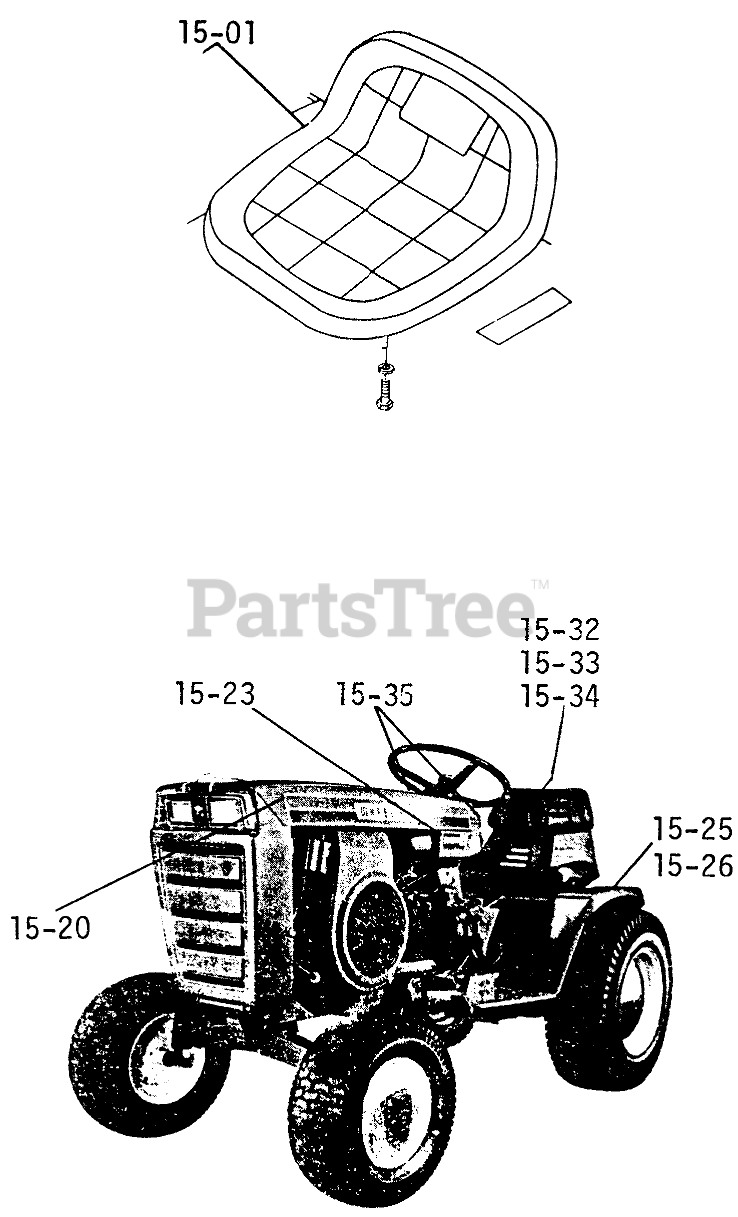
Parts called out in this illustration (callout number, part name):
15-01	Bolt Hex 5/16-18
15-01	Lockwasher
15-23	Decal-800 Automatic
15-23	Decal-800 Special
15-26	Reflector
15-35	Decal-Lift
